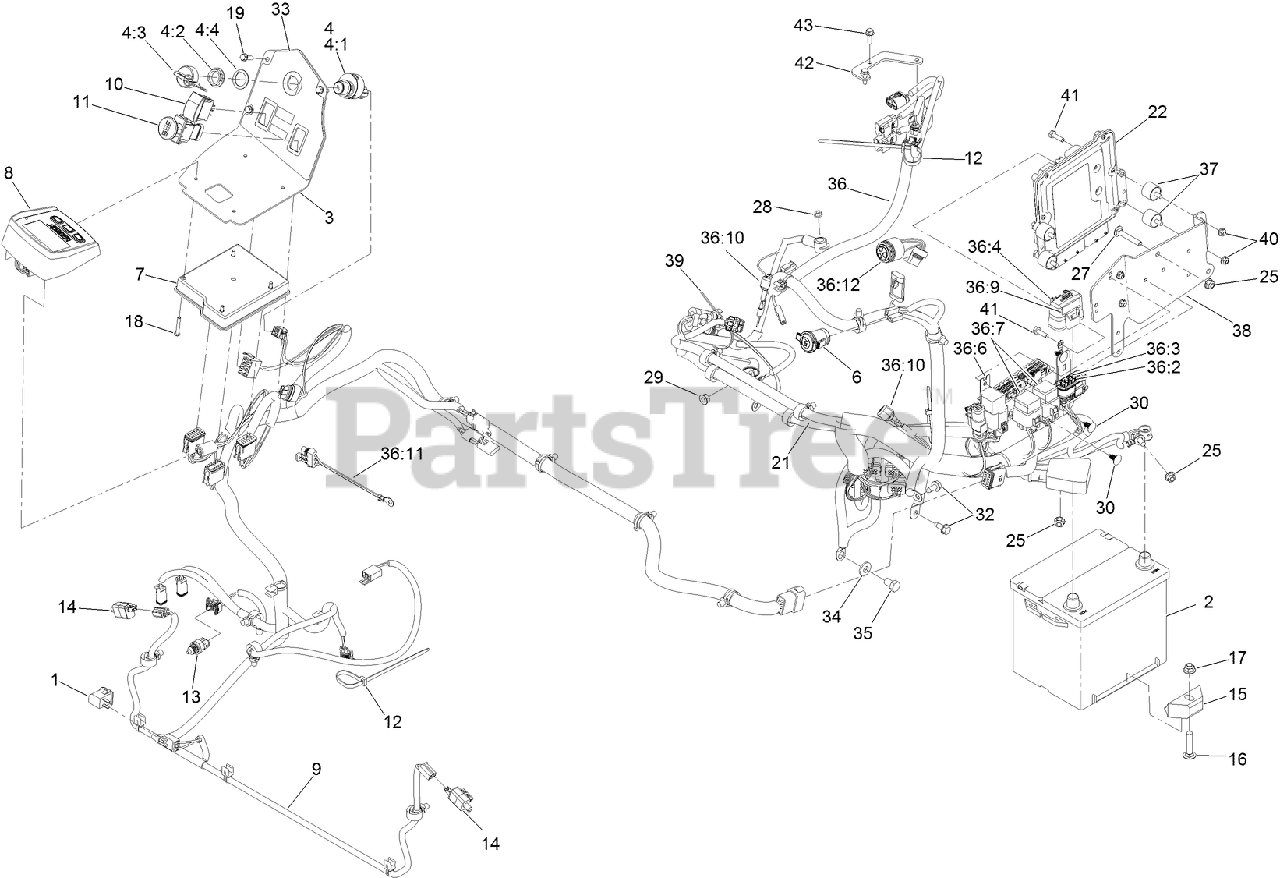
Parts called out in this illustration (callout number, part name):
1	SWITCH-BAIL
2	BATTERY-DRY
3	PLATE-CONSOLE
4	IGNITION SWITCH ASM
4:1	Deck ASM
4:2	NUT-MOUNTING
4:3	IGNITION KEY SET
4:4	WASHER-BACKUP
6	PORT-POWER, 12V
7	MODULE
8	MODULE-HORIZON
9	HARNESS-WIRE
10	SWITCH
11	SWITCH-PTO, SEALED
12	TIE-PLASTIC
13	SENSOR-TEMPERATURE
14	SWITCH
15	RETAINER-BATTERY
16	SCREW-HH
17	NUT-HF, NI
18	SCREW-PPH
19	SCREW-HWH
21	CABLE-BATTERY
22	CONTROLER-ENGINE
25	NUT-HF, NI
27	BOLT-CARR
28	NUT-HF
29	NUT-HF
30	PLUG-PLASTIC
32	SCREW-HWHTF
33	DECAL-CONTROL PANEL
34	WASHER-BELLEVILLE
35	SCREW-HH
36	HARNESS-WIRE
36:2	FUSE-MINI BLADE, 15 AMP
36:3	FUSE-MINI BLADE, 25 AMP
36:4	COVER-BLOCK, FUSE
36:6	RELAY-70A
36:7	RELAY-MINI
36:9	DECAL-FUSE
36:11	HARNESS-WIRE, FUSIBLE LINK
36:12	ALARM-DUAL TONE
37	MOUNT-CYLINDRICAL
38	MOUNT-CONTROL UNIT, ENGINE
39	TIE-CABLE
40	NUT-HF
41	SCREW-HH
42	BRACKET-WIRING, ENGINE
43	SCREW-HHF
